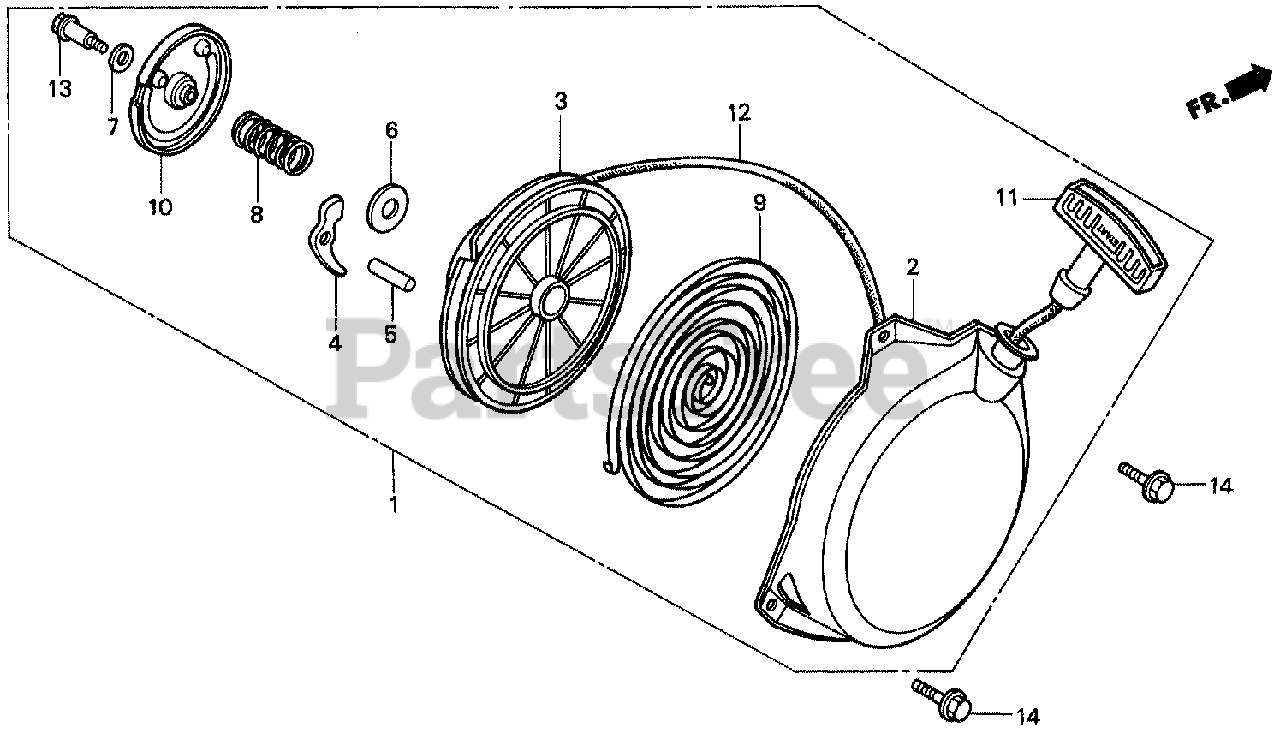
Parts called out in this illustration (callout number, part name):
1	STARTER ASSY., RECOIL
2	CASE, STARTER
3	REEL, STARTER
4	RATCHET, STARTER
5	SHAFT, RATCHET
6	PLATE A, FRICTION
7	PLATE B, FRICTION
8	SPRING, FRICTION
9	SPRING, RETURN
10	COVER, REEL STARTER
11	GRIP, STARTER
12	ROPE, STARTER (N/A: USE ALTERNATE P/N 08555-ZG921-11)
13	BOLT, REEL COVER
14	BOLT, FLANGE (6X8)
